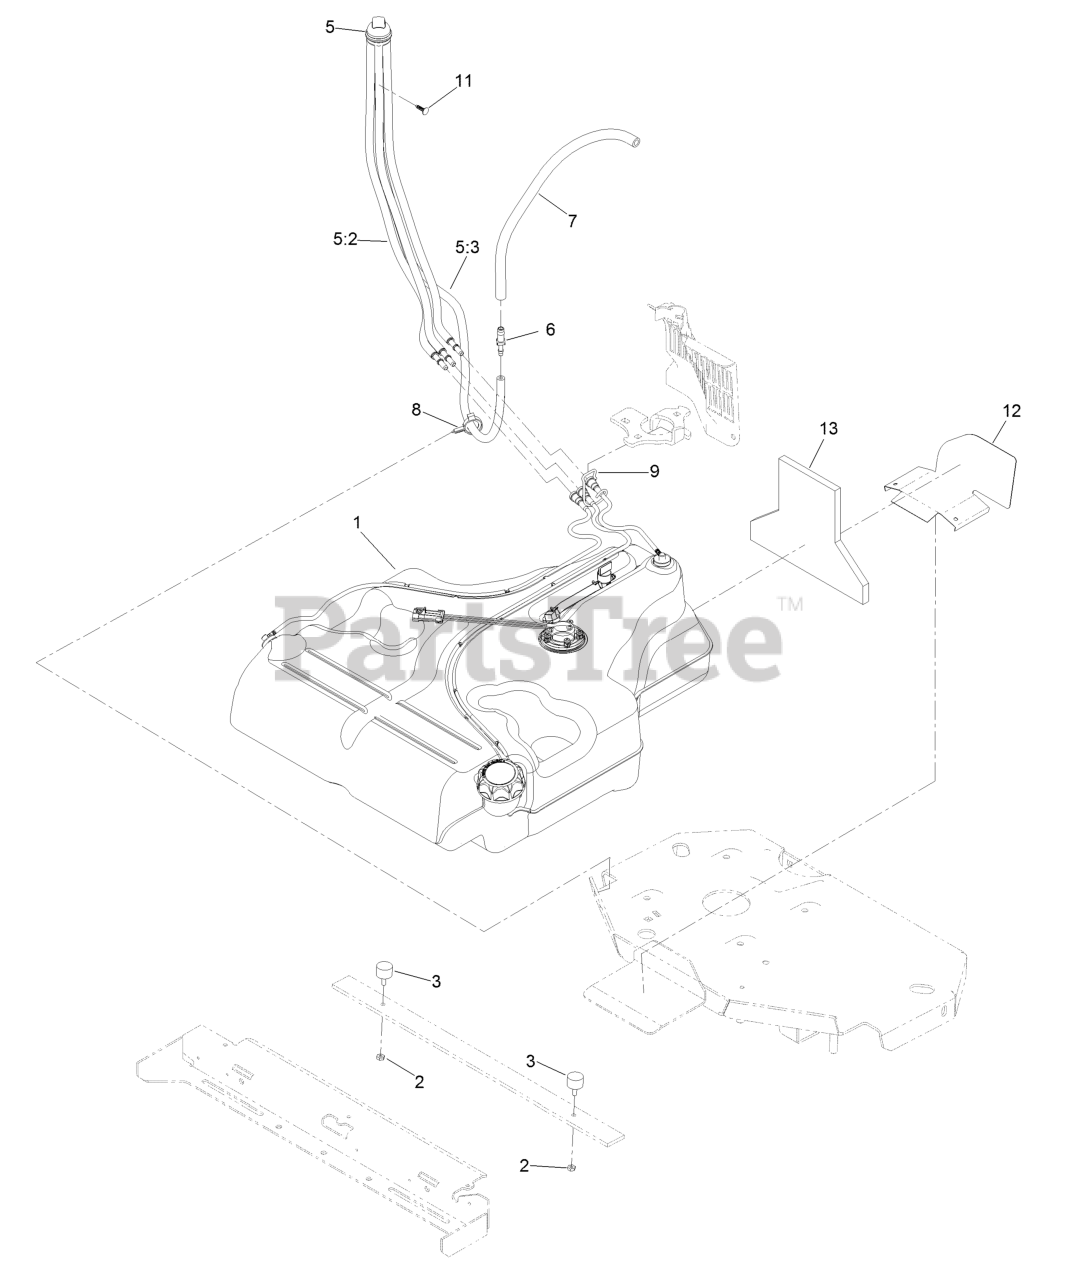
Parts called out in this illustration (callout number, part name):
1	Fuel Tank ASM
2	Nut-Jam
5	Fuel Manifold Vent ASM
5:2	Hose-Fuel
5:3	Hose-Fuel
6	Fitting-Straight
7	Hose-Fuel
8	Clamp-Hose
9	Retainer-Line, Vapor
11	Plug-Plastic
12	Guard-Exhaust
13	Insulation-Foam, Fuel Tank
